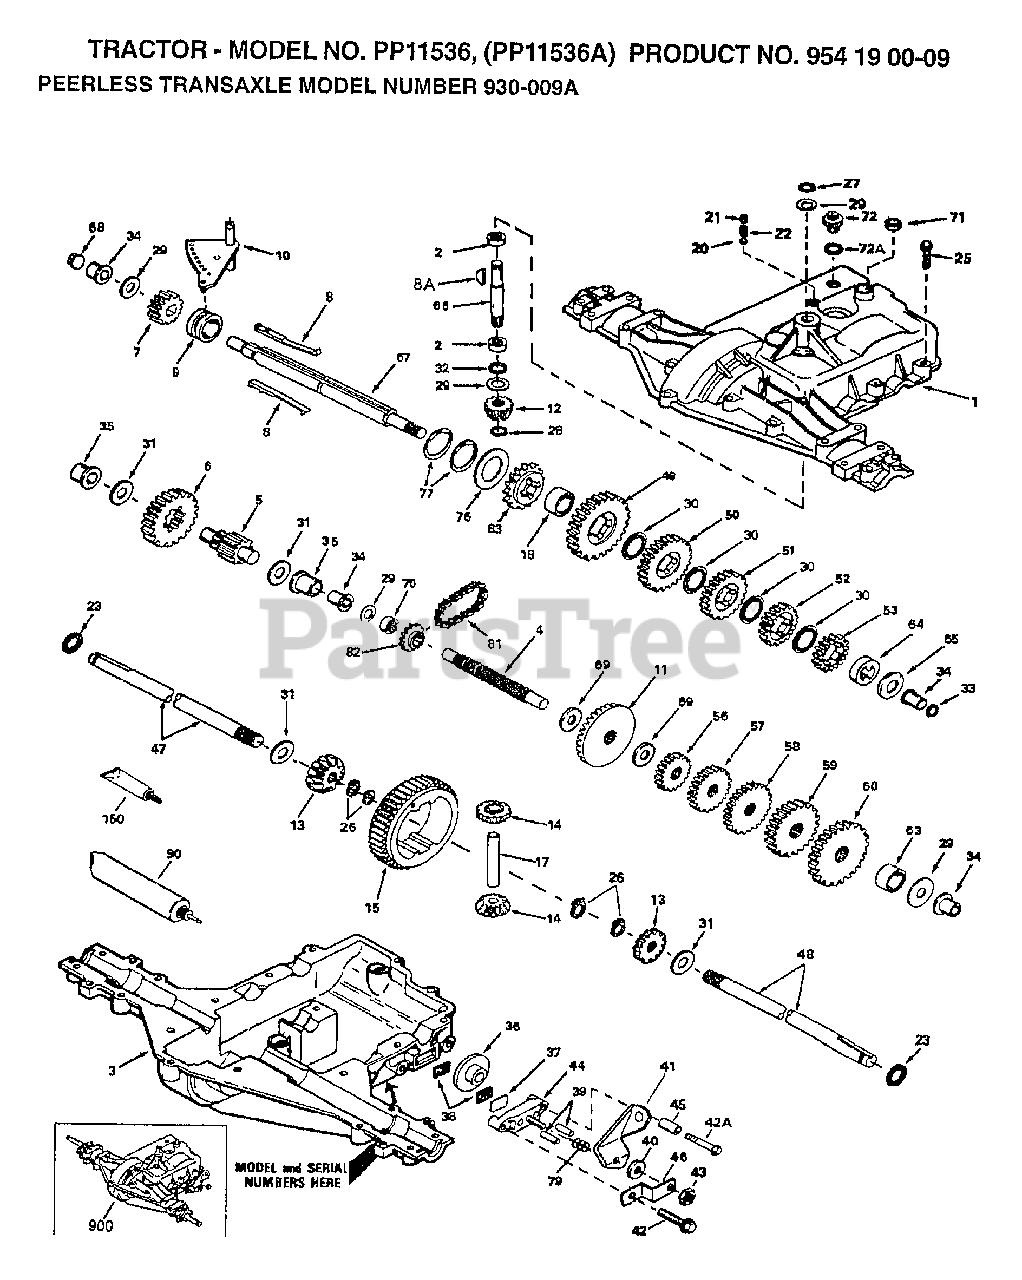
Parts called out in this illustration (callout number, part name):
1	TRANSAXLE COVER
2	BEARING, NEEDLE
3	TRANSAXLE CASE
4	SHAFT, COUNTER
5	OUTPUT SHAFT AND PINION
6	GEAR, OUTPUT
7	GEAR, SPUR, 15 TEETH
8A	KEY, WOODRUFF
9	COLLAR, SHIFTER
10	ROD & FORK ASSY, SHIFT
11	GEAR, BEVEL, 42 TEETH
12	BEVEL PINION, INPUT
13	GEAR, BEVEL
14	GEAR, BEVEL, PINION
18	SPACER, NEUTRAL
20	BALL STEEL, 5/16" DIA.
21	SCREW, 3/8-16 X 3/8"
25	SCREW, 1/4-20 X 1-1/4
26	RING RETAINER
27	RING, RETAINER
28	RETAINING RING
29	WASHER THRUST
30	WASHER THRUST
33	SEAL, SQUARE CUT
34	BUSHING, FLANGED
35	BUSHING, FLANGED
36	DISK, BRAKE
37	PLATE BRAKE PAD
41	BRAKE LEVER
42	SCREW, 1/4-20 X 1-1/4
42A	SCREW, 1/4-20 X 2-1/4
43	LOCKNUT 5/16-24
44	HOLDER BRAKE PAD
46	BRKT BRAKE LEVER
49	GEAR, SPUR, 37 TEETH
50	GEAR, SPUR, 30 TEETH
51	GEAR, SPUR, 25 TEETH
52	GEAR, SPUR, 22 TEETH
53	GEAR, SPUR, 19T
56	GEAR, SPUR, 12 TEETH
57	GEAR, SPUR, 20 TEETH
58	GEAR, SPUR, 25 TEETH
59	GEAR, SPUR, 28 TEETH
60	GEAR, SPUR, 31 TEETH
65	WASHER, THRUST
66	SHAFT, INPUT
67	SHAFT, BRAKE, 4 KEYED
69	WASHER THRUST
71	SEAL SQUARE CUT
72	THREADED PLUG 9/16-18
76	WASHER, THRUST
77	INVERTED RETAINING RING
81	CHAIN, ROLLER
82	SPROCKET 9T
83	SPROCKET 18T (REV)
90	GREASE BENTONITE, 32 OZ.
150	GASKET ELIMINATOR
900	REPLACEMENT TRANSAXLE
